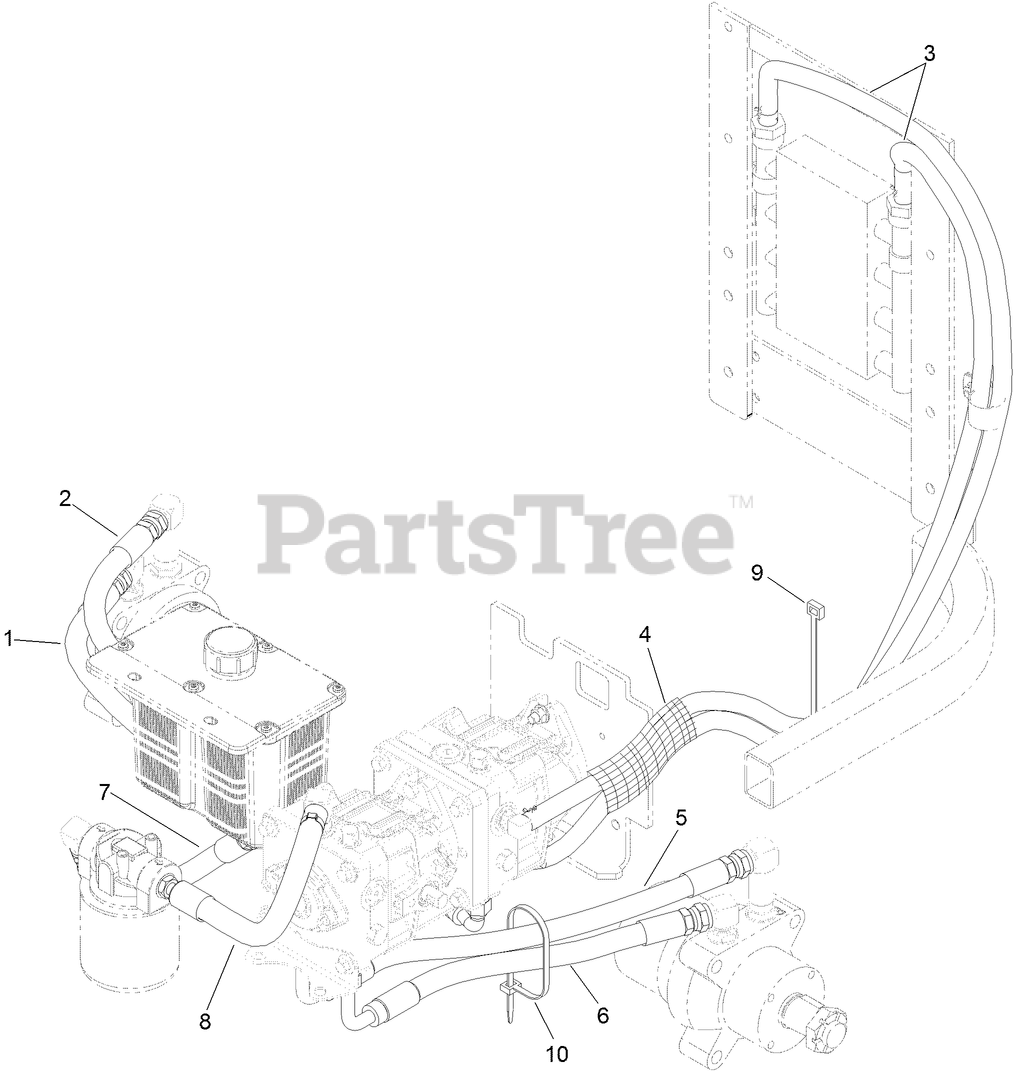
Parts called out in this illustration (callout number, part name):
1	HYDRAULIC HOSE ASM
2	HYDRAULIC HOSE ASM
3	HOSE-HYDRAULIC
4	SLEEVE-FABRIC
5	HYDRAULIC HOSE ASM
6	HYDRAULIC HOSE ASM
7	HYDRAULIC HOSE ASM
8	HYDRAULIC HOSE ASM
9	TIE-PLASTIC
10	CABLE TIE-PLASTIC
